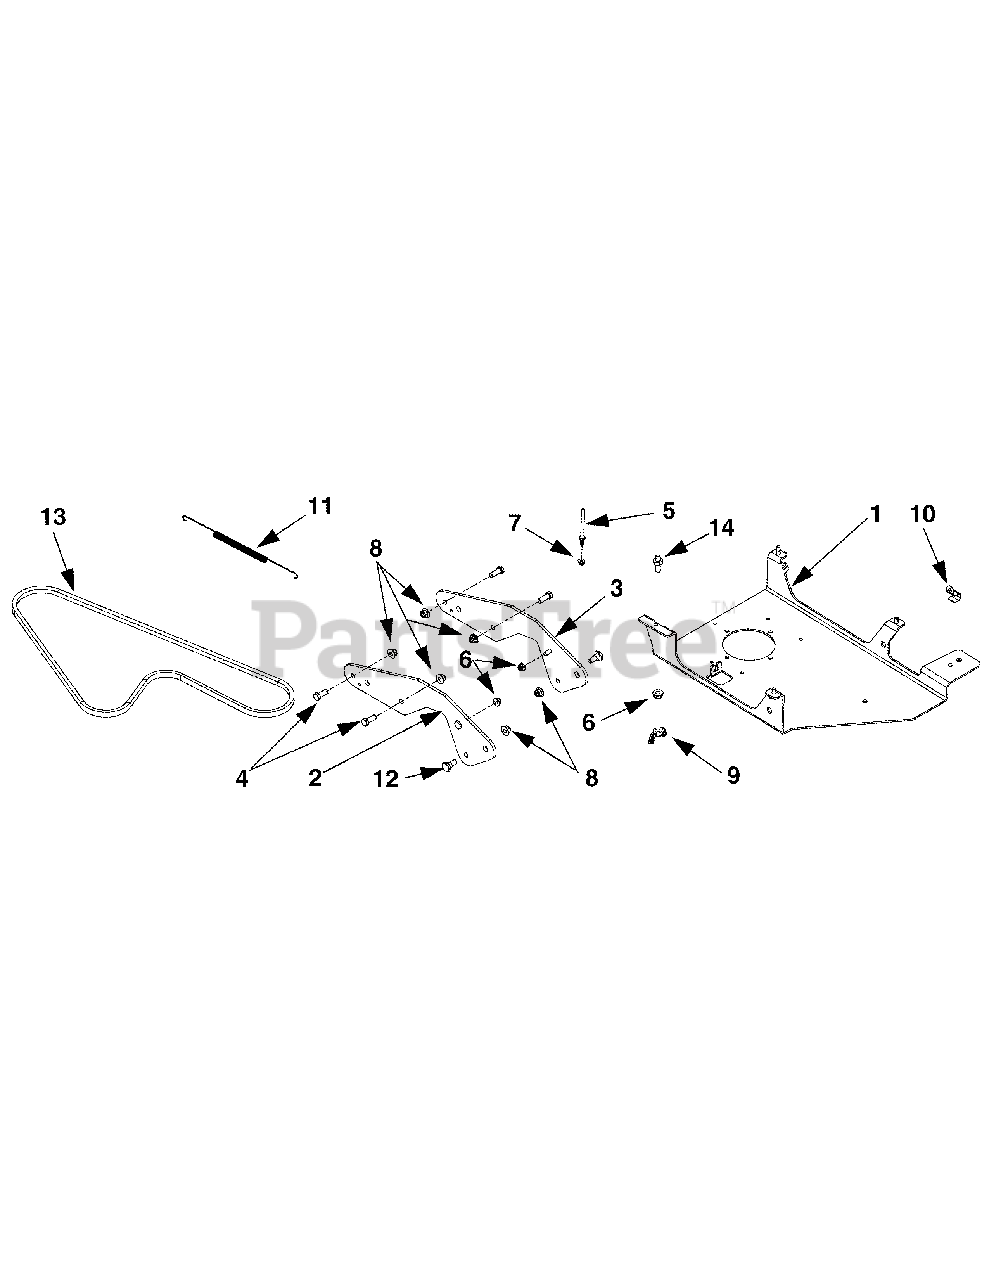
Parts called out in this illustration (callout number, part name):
1	BRACKET: ASSEMBLY: UNDERCARRIAGE
2	BRACKET: ASSEMBLY: SNOW LT-5 RH
3	BRACKET: ASSEMBLY: SNOW LT-5 LH
4	SCREW: HEX HD: 3/8"-16 x 1.00: GR5: STD
5	KEEPER: BELT:.25 DIA x 3.0
6	NUT: FLANGELOCK: 5/16"-18: GRF: NYLON
7	NUT: FLANGELOCK: 1/4"-20: GRF: NYLON
8	NUT: FLANGELOCK: 3/8"-16: GRF: NYLON
9	NUT: WING: 5/16"-18 NYLOK
10	CLAMP:16MM
11	SPRING: EXTENSION: .50 DIA x 12.00 LG
12	SCREW: SHOULDER: .498 x .340: 3/8"-16
13	BELT: V TYPE: A SECTION x 66.90"
14	PIN: 5/16"-18
